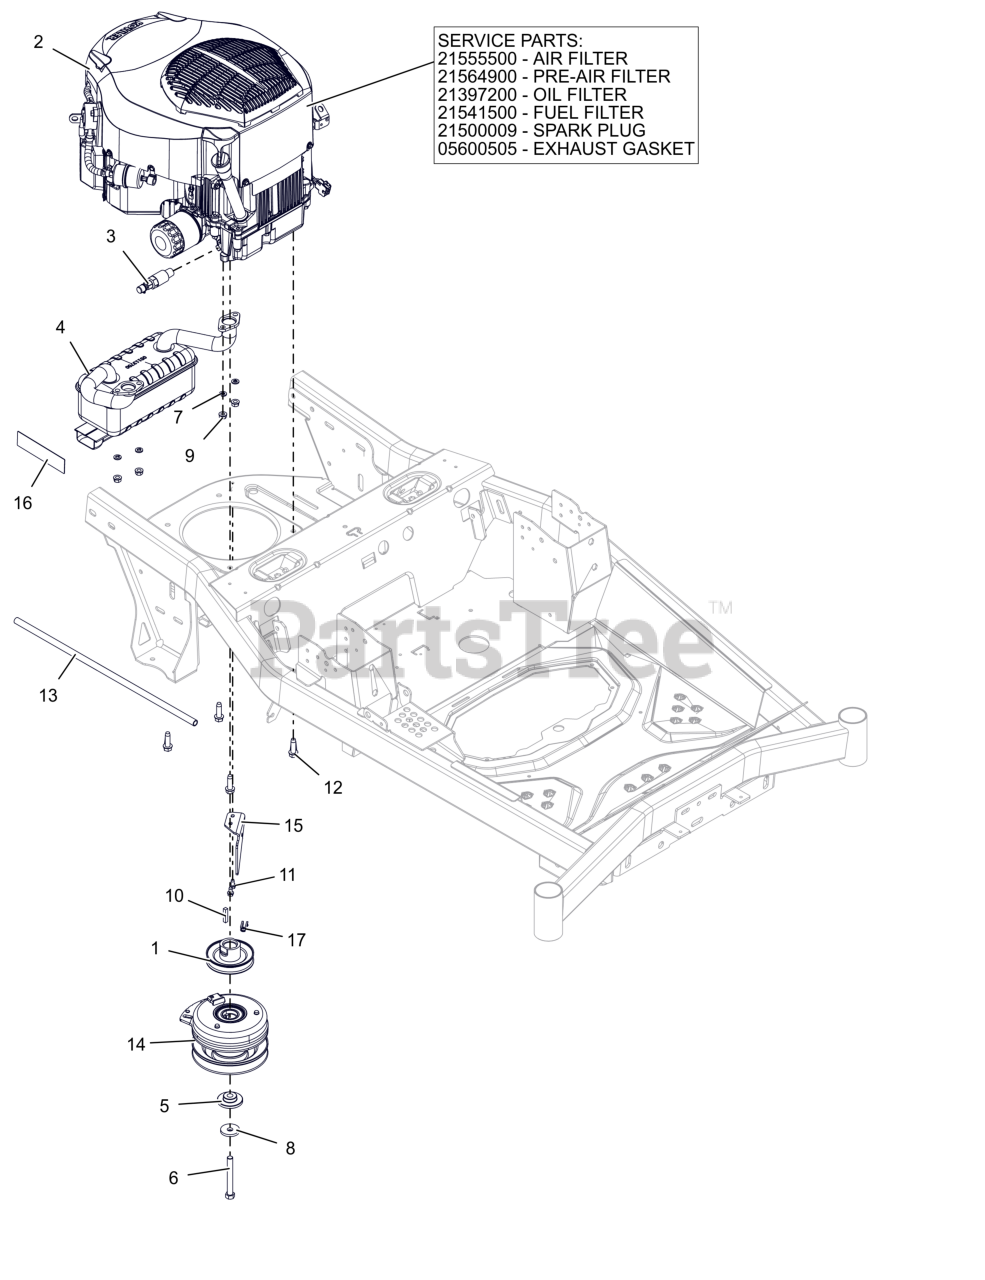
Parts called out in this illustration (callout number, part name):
1	WLDMT, PULLEY 3.75 OD X 1.003 ENGINE
2	ENGINE, KOHLER - KT730
2	AIR CLEANER, KOHLER
2	PRE-CLEANER, KOHLER
2	FILTER, OIL - KOH CV20
2	FILTER, FUEL
2	PLUG, SPARK KOHLER
2	GASKET, MUFFLER COURAGE TWIN
3	DRAIN, OIL
4	MUFFLER, KOHLER
5	BSHG-FLG .469X1.06X.574X2.0
6	BLT, HEX 0.4375-20X3.5 G8 ZCC NT
7	WSHR,LK-REG .312X.078 ZCC
8	WASHER, 7/16" SPRING DISK
9	NUT-LK-TOP-FLG .312-18 GF ZCC
10	KEY-SQ .25 X 1.25 X .25 SAE
11	SCR-TAP .25-20X.50 HWH ZCC
12	SCR,TAP .375-16X1.25HWH TR ZCC
13	HOSE, OIL DRAIN
14	CLUTCH- WARNER IXR-18211
15	BRKT- CLUTCH STOP
16	TAPE- HEAT DEFLECTOR
17	BSHG, CLUTCH
